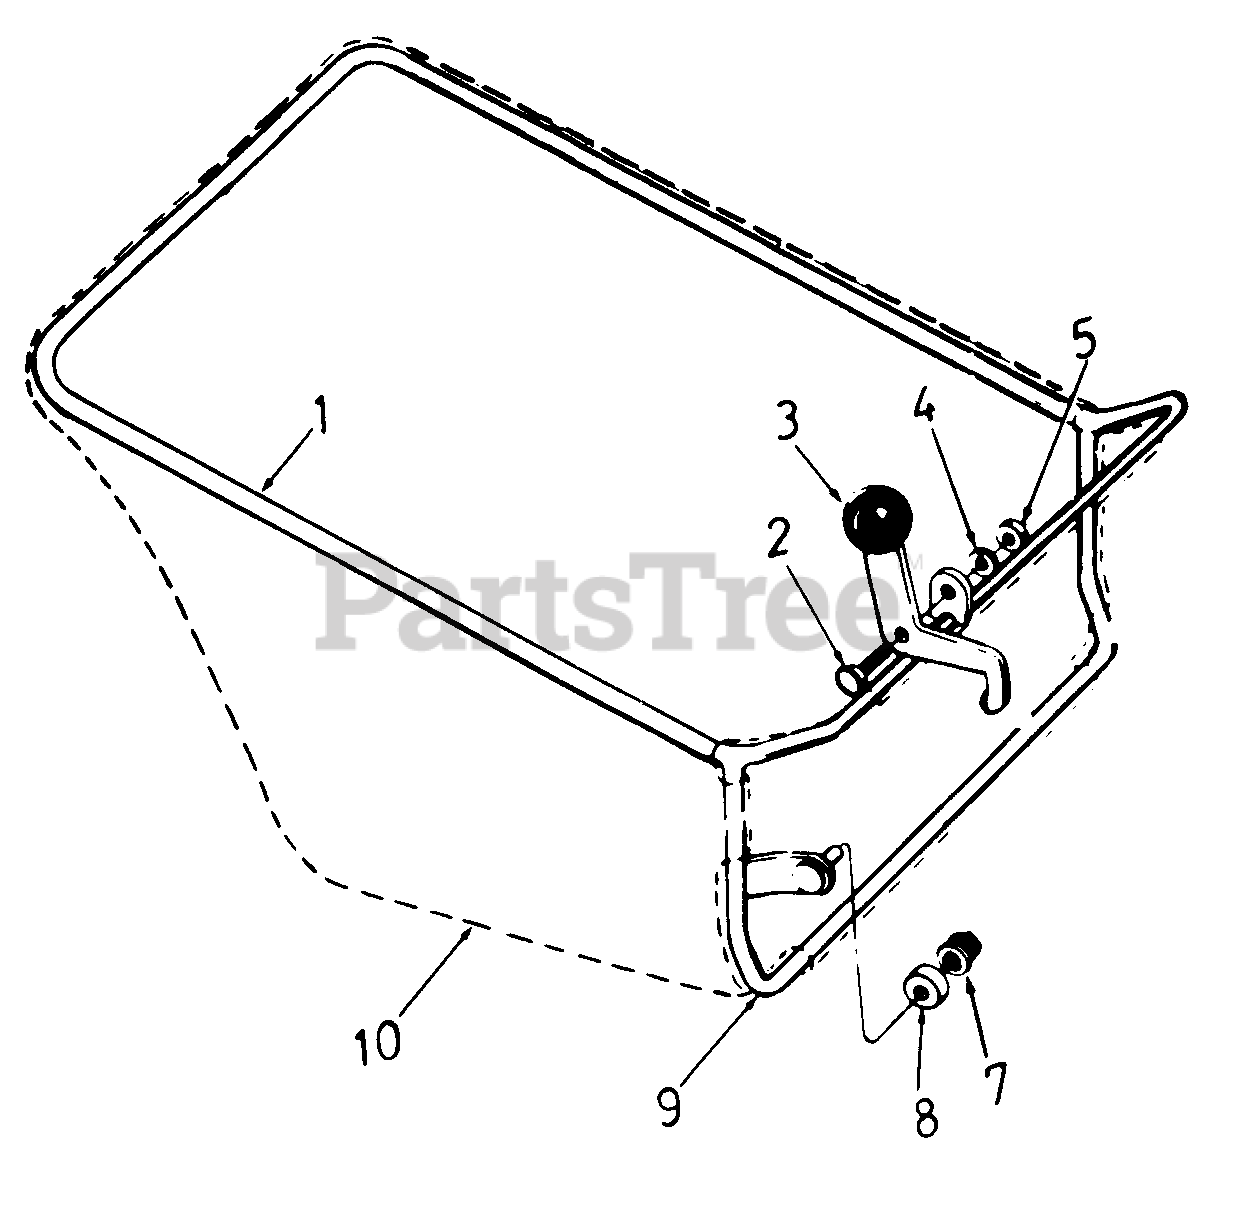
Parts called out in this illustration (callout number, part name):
1	Upper Frame
2	Upper Frame
3	Shld. Scr. .437 Dia. x .180
4	Cam Lever Grip Ass'y.
5	L-Wash. 5/16" Scr.
7	Push Cap
8	Plastic Roller
9	Lower Frame Ass'y.
10	Grass Bag
